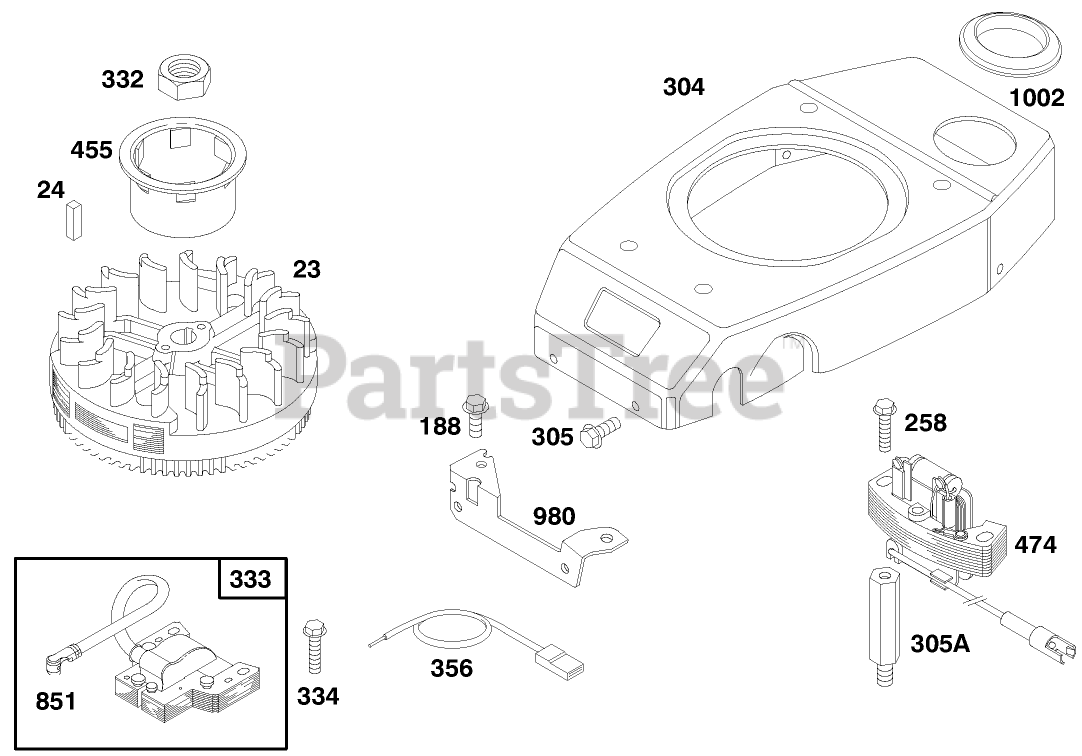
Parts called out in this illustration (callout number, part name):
23	FLYWHEEL - MAGNETO
24	KEY - FLYWHEEL
37	GUARD - FLYWHEEL
305	SCREW - HEX HEAD
332	NUT - HEXAGON
356	WIRE - GROUND
980	BRACKET-BLOWER HSG
